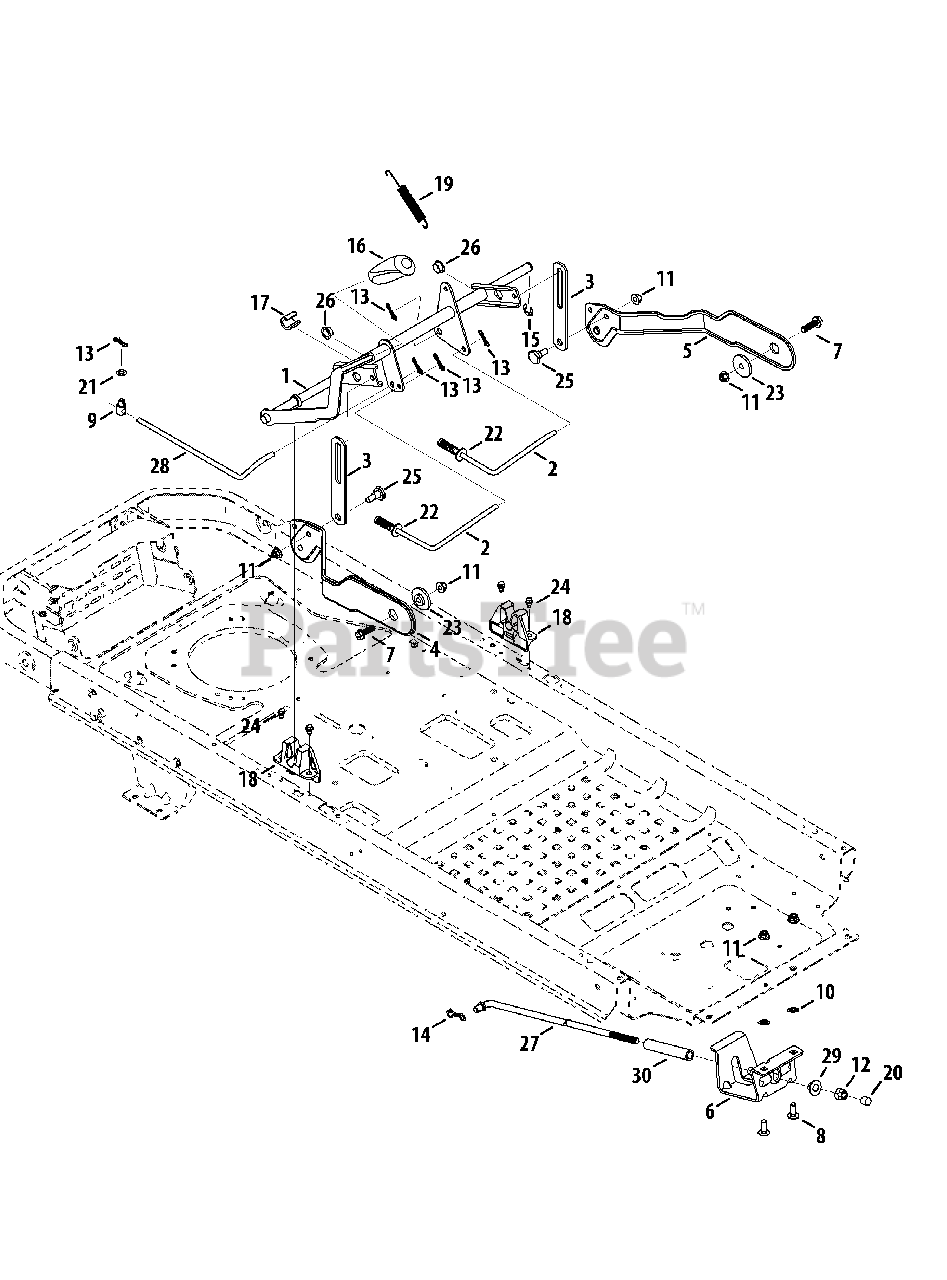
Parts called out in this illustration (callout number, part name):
1	Deck Lift Shift Assembly
3	Lift Link Plate
4	Deck Lift Plate, RH
5	Deck Lift Plate, LH
6	Rod Support Mounting Bracket
7	Hex Washer Screw, 3/8-16 x 1.250
8	Carriage Bolt, 3/8-16 x 1.00
9	Ferrule, 3/8-24 x .375
10	Push Nut, 3/8
11	Flange Lock Nut, 3/8-16
12	Flange Lock Nut, 1/2-13
13	Bow-Tie Cotter Pin
14	Bow-Tie Cotter Pin
15	E-Type Ring, .750
16	Grip, .50 ID
17	Spacer, .76 ID x .750 LG
18	Deck Lift Bracket
19	Extension Spring, .63 Dia. x 4.95 LG
21	Washer, .375 x .700 x .030
22	Flat Washer, .344 x 1.00 x .063
23	Shoulder Spacer, .884 x .190
24	Shoulder Screw, .500 x 1/4-20
25	Shoulder Screw, .500 Dia. x .434
26	Flange Bearing, .751 x 1.125 x .375
27	Deck Lift Rod
28	Brake Rod
29	Deck Lift pivot Cup
30	Nylon Sleeve, .55 ID x 4.50 LG
